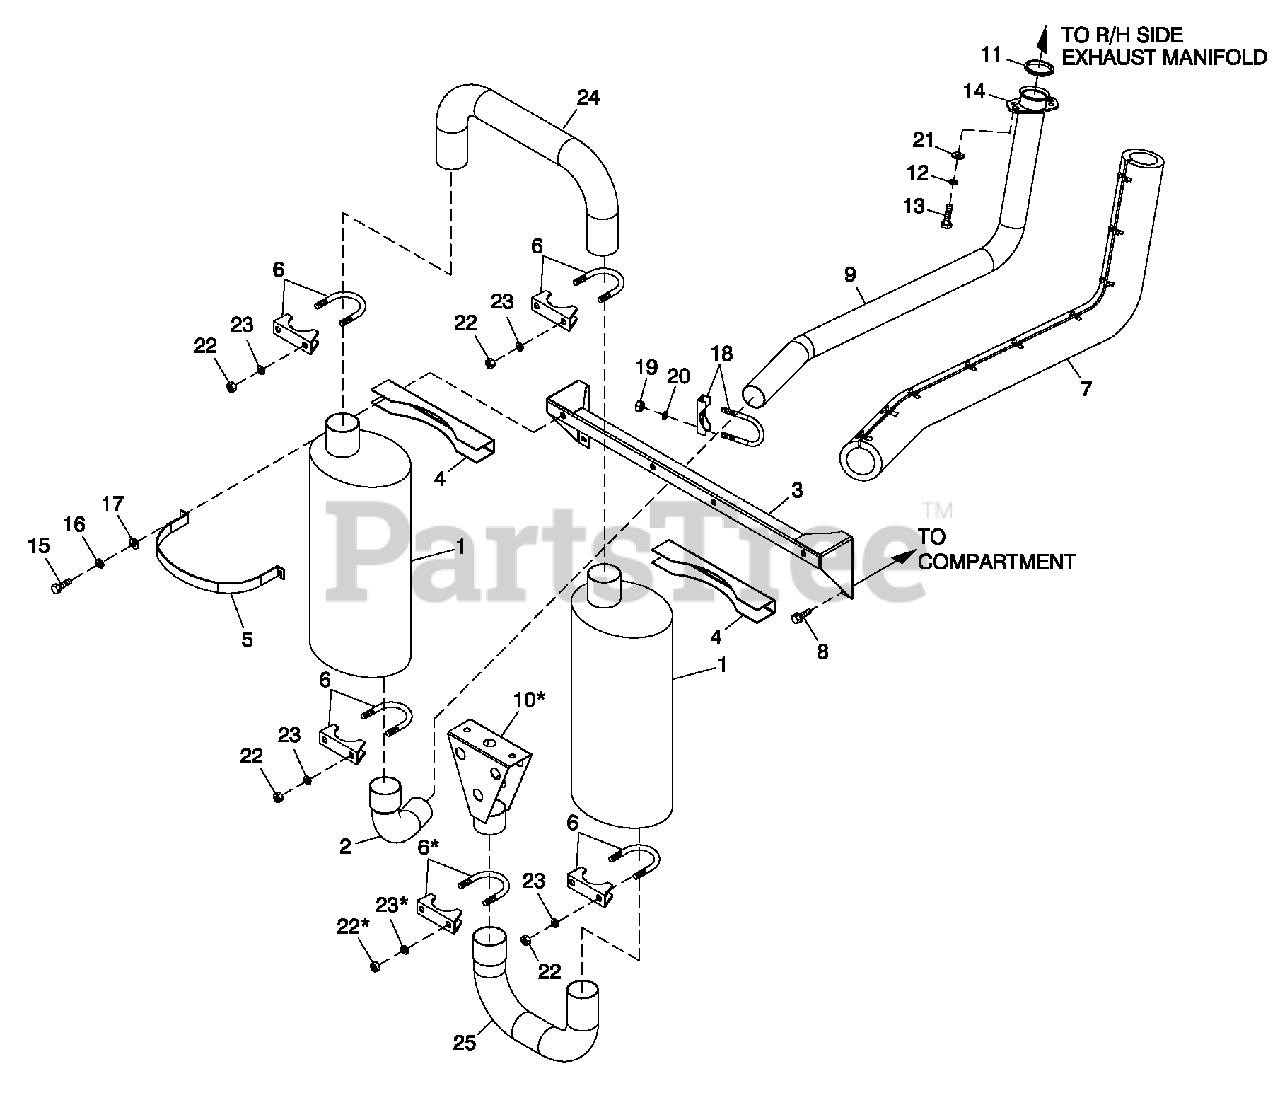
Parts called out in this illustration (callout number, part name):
1	MUFFLER 7" X 9" X 18-1/2" 2" IN/OUT
2	EXHAUST ELBOW 2 1/4 OD 2 1/2OD
3	BRACKET MUFFLER
4	MUFFLER BRACKET STIFFENER
5	MUFFLER STRAP
6	BOLT U 3/8-16 X 2.62
7	EXHAUST BLANKET 988MM (C2)
8	SCREW THF M6-1 X 16 N WA Z/JS
9	PIPE EXHAUST G2
10	DIFFUSER EXHAUST WELDMENT
11	GASKET EXHAUST RING
12	WASHER LOCK 3/8 SS
13	SCREW HHC 3/8-16 X 1-3/4 SS
14	EXHAUST FLANGE 2" PIPE
15	SCREW HHC M6-1.0 X 35 G8.8 BLK
16	WASHER LOCK M6-1/4
17	WASHER FLAT 1/4-M6 ZINC
18	BOLT U 5/16-18 X 2.25
19	NUT HEX 5/16-18 STEEL
20	WASHER LOCK M8 SS
21	WASHER FLAT 3/8 SS
22	NUT HEX 3/8-16 STEEL
23	WASHER LOCK 3/8 SS
24	PIPE EXHAUST CROSSOVER
25	PIPE EXHAUST MUFFLER OUT
